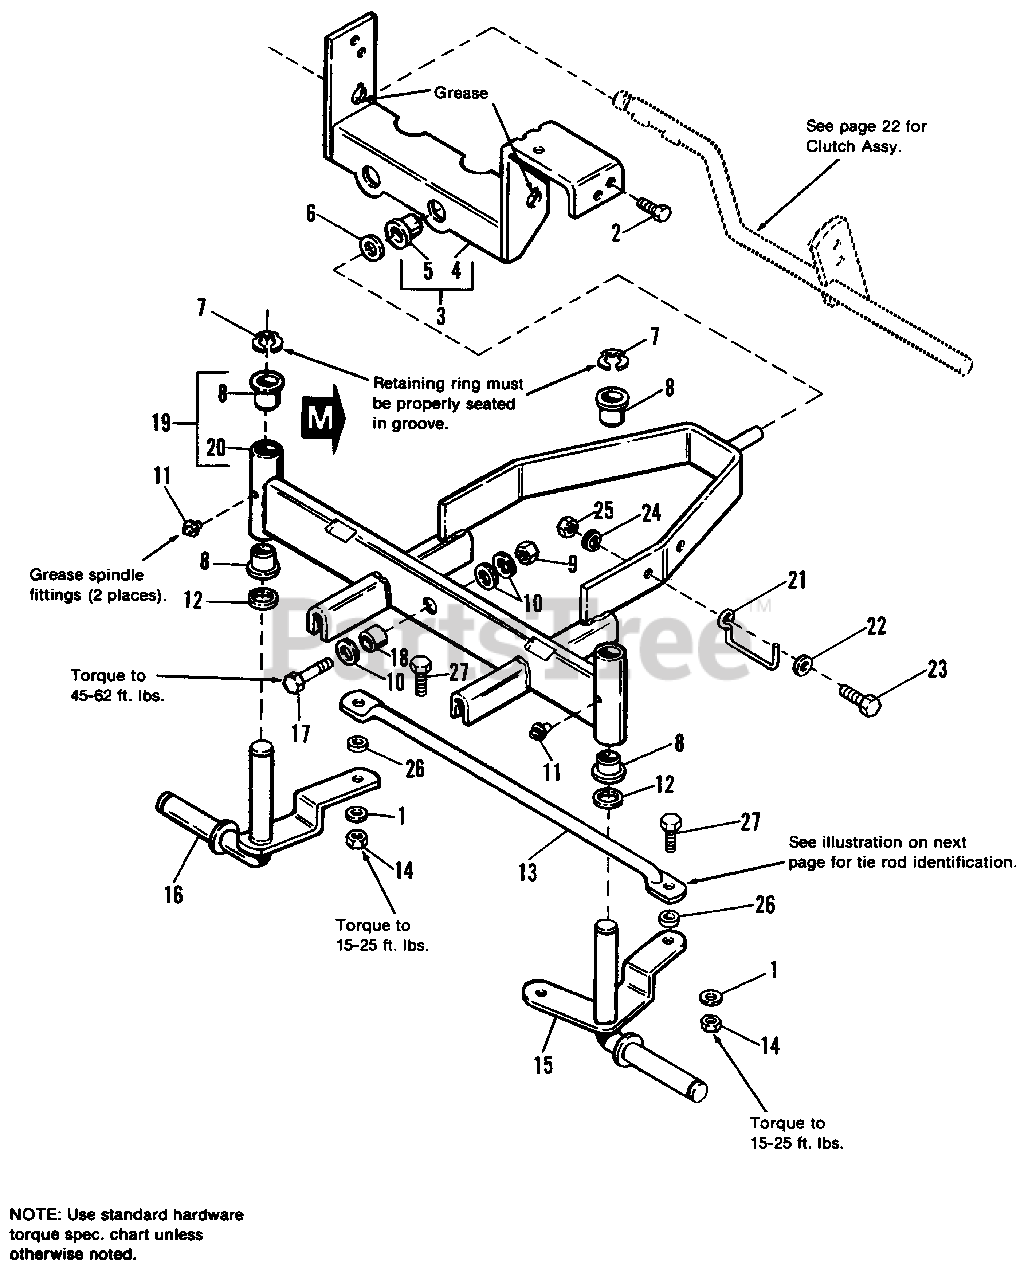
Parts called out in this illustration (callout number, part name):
1	WASHER
2	SCREW, Hex, Taptite, 5/16-18 x 3/4
3	SUPPORT ASSY., Axle, Rear w/Bushing (Incl. Ref. Nos. 4 & 5)
6	WASHER, 3/8
9	LOCKNUT, Hex, 1/2-13
10	WASHER, 9/16
11	FITTING, Grease
12	WASHER
13	ROD ASSY., Tie
14	LOCKNUT, Hex, 3/8-16
15	SPINDLE ASSY., L.H.
16	SPINDLE ASSY., R.H.
17	CAPSCREW, Hex Hd., 1/2-13 x 1-1/2
18	SPACER
19	AXLE ASSY., Front (Incl. Ref. Nos. 8 & 20)
21	GUIDE, Drag Link
22	WASHER, 5/16
23	CAPSCREW, Hex Hd., 5/16-18 x 1
24	LOCKWASHER, 5/16
25	NUT, Hex, 5/16-18
27	CAPSCREW, 3/8-16 x 1
